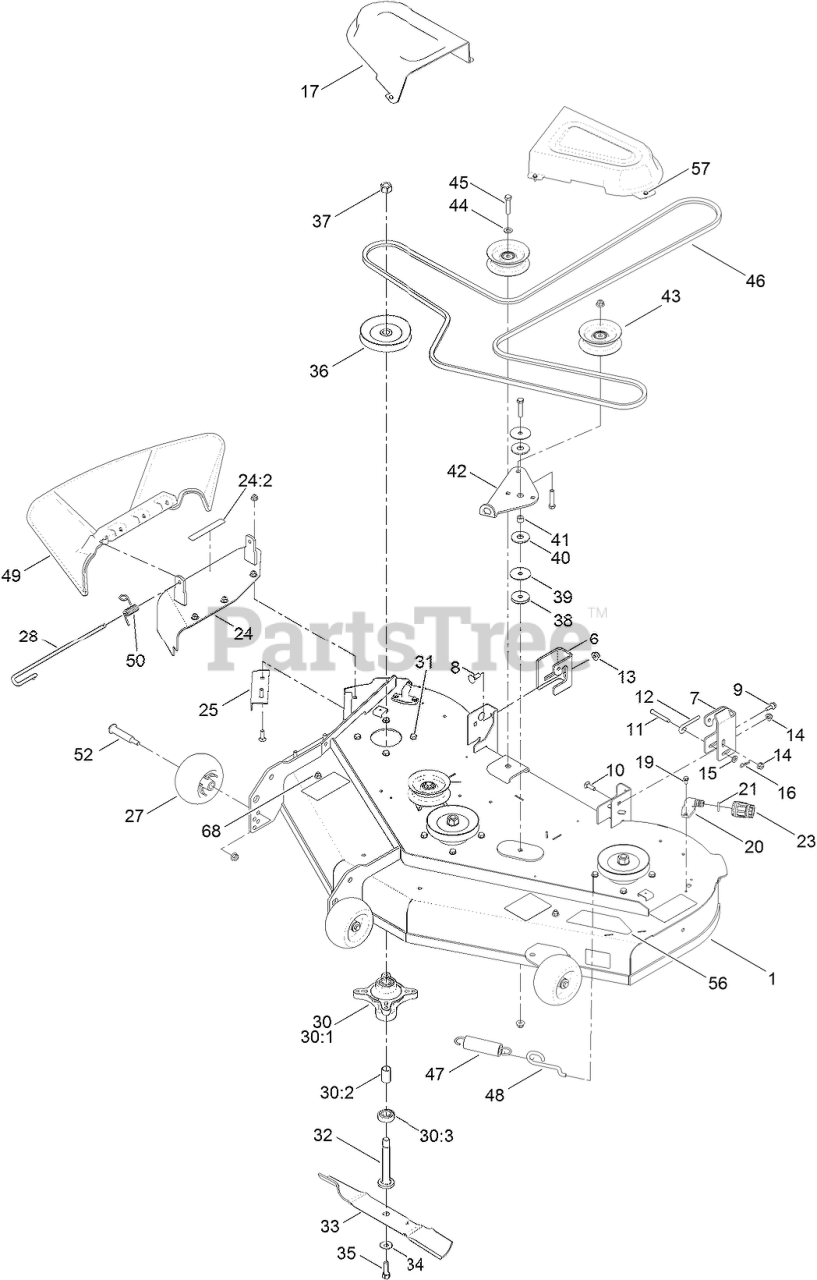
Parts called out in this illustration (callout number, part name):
1	DECK AND DECAL ASM
6	BRACKET-HANGER, RH
7	BRACKET-HANGER, LH
8	BOLT-CARR
9	SCREW-SHOULDER, HHF
10	SCREW-CARR
11	PIN-CLEVIS
12	ROD-LEVEL, DECK
13	NUT-HF, NI
14	NUT-HF, NI
15	WASHER-PLAIN
16	PIN-COTTER
17	COVER-BELT
19	SCREW-HWH
20	FITTING-WASHOUT
21	O-RING
23	CONNECTOR-HOSE
24	COVER ASM W/DECAL
24:2	DECAL-DANGER
25	BAFFLE-CUTOFF
27	ROLLER-SCALP, ANTI
28	PIN-CHUTE
30	SPINDLE ASM
30:1	SPINDLE
30:2	SPACER
30:3	BEARING-BALL
31	SCREW-TAPTITE
32	SHAFT-SPINDLE
33	BLADE-HI LIFT
34	WASHER-BELLEVILLE
35	SCREW-HH
36	PULLEY
37	NUT-HEX
38	WASHER-PLAIN
39	WASHER
40	WASHER-FRICTION, COMPOSITE
41	SPACER
42	ARM-IDLER
43	PULLEY-IDLER, FLAT
44	WASHER-FLAT
45	SCREW-HH
46	V-BELT
47	SPRING-EXTENSION
48	HOOK-RETURN, SPRING
49	DEFLECTOR-DISCHARGE
50	SPRING-TORSION
52	BOLT-SHOULDER
56	DECAL-DECK
57	SCREW-TAPTITE
68	SCREW-HH
